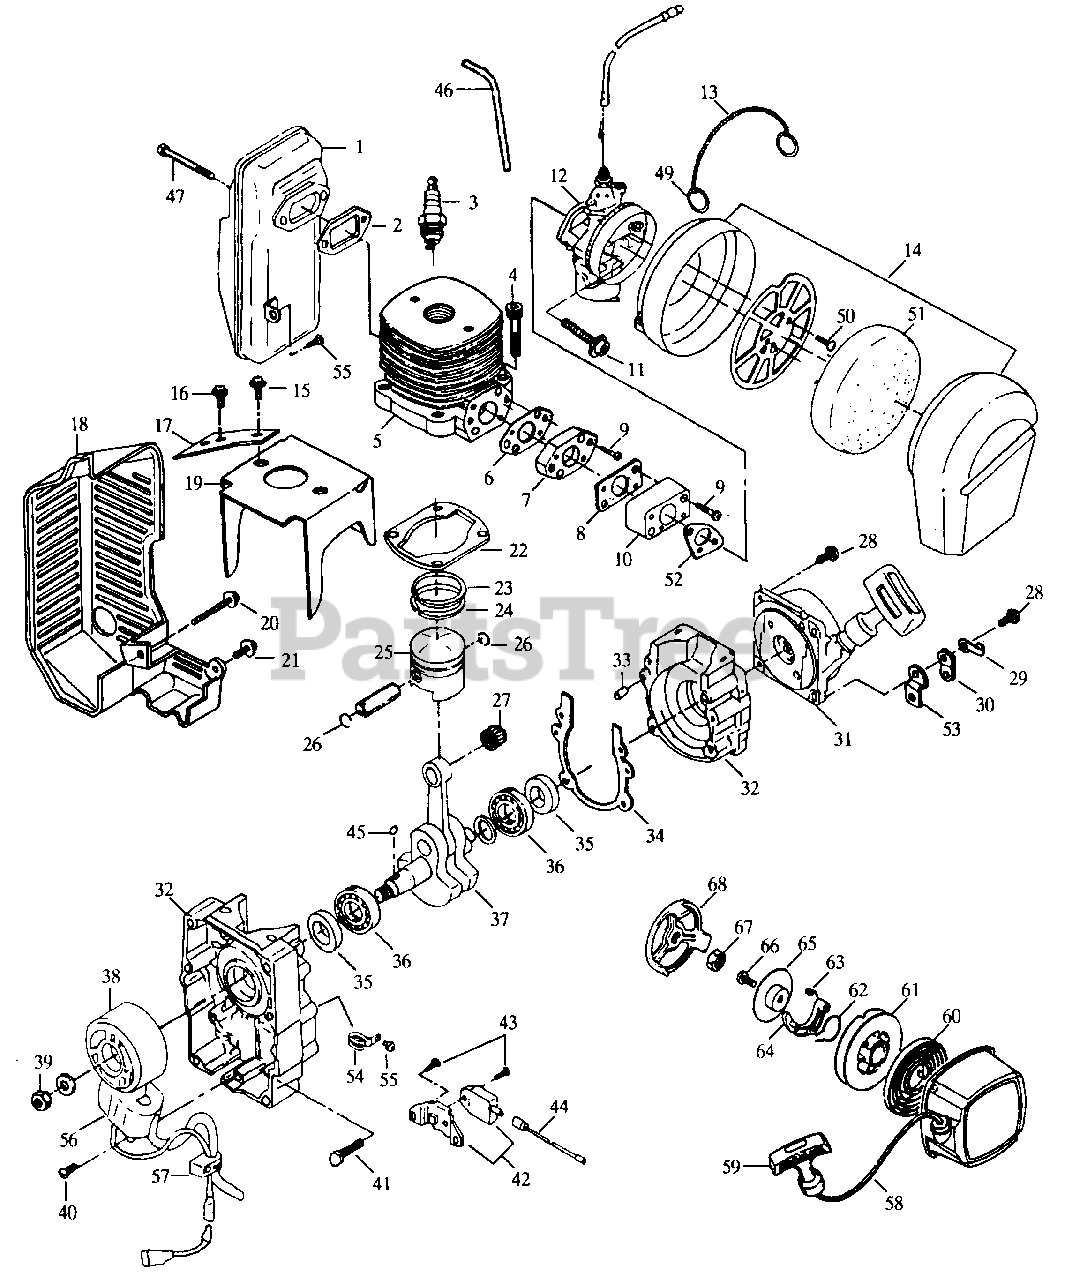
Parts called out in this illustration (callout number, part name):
1	Muffler Ass'y.
2	Muffler Gasket
3	Spark Plug
5	Cylinder
6	Carburetor Gasket
8	Insulator Gasket
9	Screw & Washer
10	Insulator
11	Screw & Washer
12	Carburetor
14	Air Cleaner Ass'y.
15	Screw & Washer
16	Screw & Washer
18	Muffler Cover
19	Cylinder Cover
21	Screw & Washer
22	Cylinder Gasket
23	Ring Top
24	Ring Top
25	Piston Ass'y.
26	Piston Pin Clip
27	Bearing Needle
28	Screw & Washer
31	Starter Recoil
32	Crankcase Ass'y.
33	Pin Dowel
34	Crankcase Gasket
35	Oil Seal
36	Ball Bearing
37	Crankshaft Ass'y.
40	Bolt & Washer
41	Screw & Washer
42	Transister Unit
43	Screw & Washer
44	Lead Wire
45	Woodruff Key
46	Fuel Tube
50	Screw & Washer
51	Element Cleaner
52	Carburetor Gasket
55	Screw & Washer
56	Ignition Coil
58	Starter Rope
59	Starter Knob
62	Friction Spring
63	Return Spring
65	Friction Plate
68	Starter Pulley
